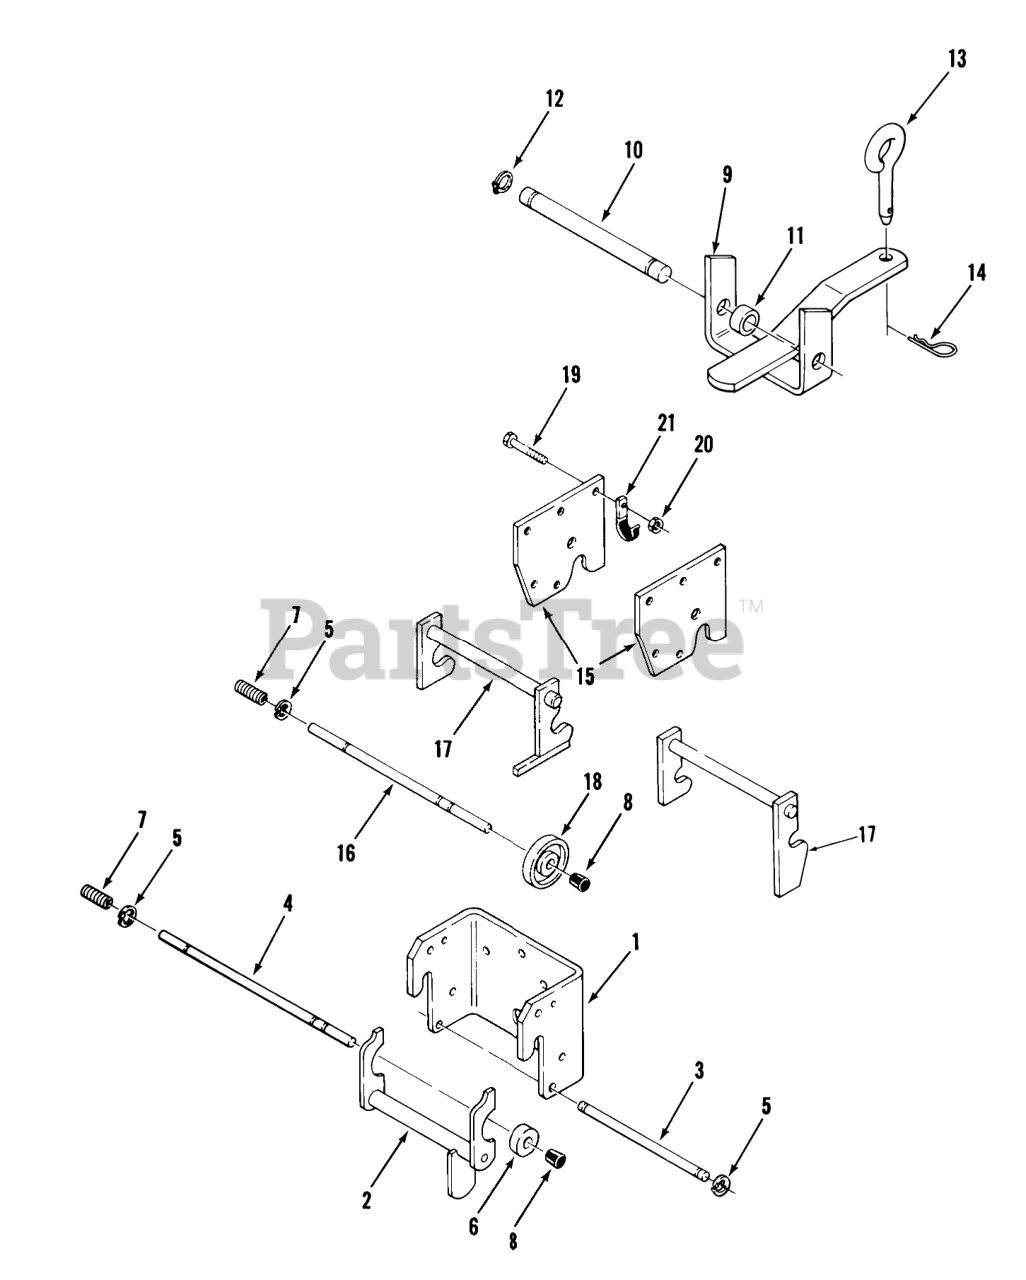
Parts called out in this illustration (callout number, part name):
1	Front Hitch
2	Assy-Latch
3	ROD-LATCH PIVOT
4	ROD-LOCK
5	RING-RETAINING
7	SPRING
8	CAP-ROD, PLUNGER
9	Hitch
10	PIN-STATIONARY HITCH
11	Spacer
12	E-RING
13	PIN-TOOL
14	Hairpin Cotter
15	Hitch Plate
17	ASSY MID HITCH LA R
17	ASSY LATCH HITCH R
19	Bolt
19	Bolt 3/8-16 x 1
20	NUT
21	CLIP
